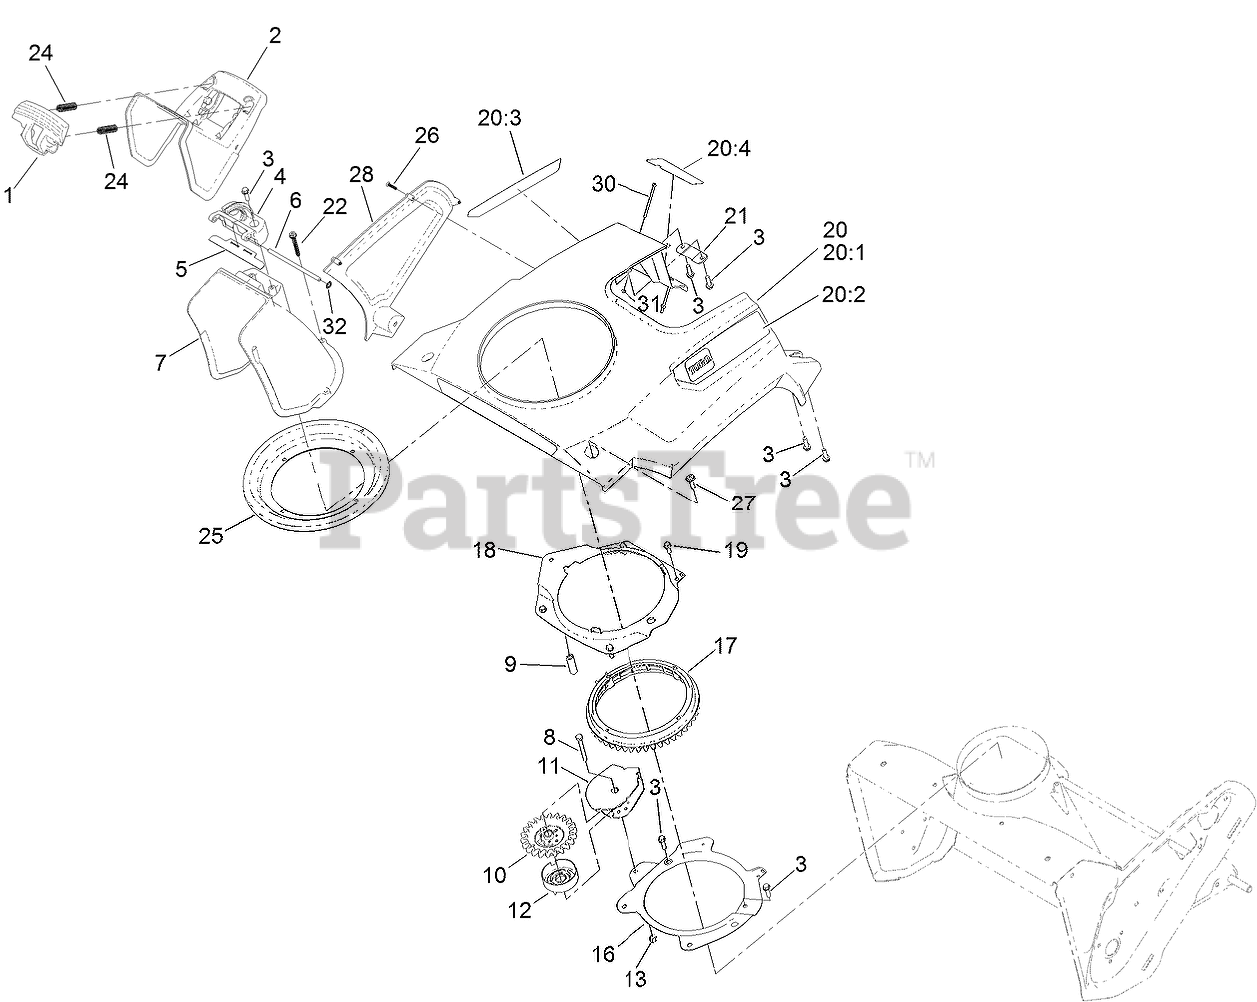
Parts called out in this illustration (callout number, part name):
1	TRIGGER-DEFLECTOR
2	DEFLECTOR-CHUTE, CE
3	SCREW-HWH
4	HINGE-RATCHET, DEFLECTOR
5	SEAL-DEFLECTOR
6	HINGE PIN-DEFLECTOR
8	SCREW-HH
9	SPACER-SLEEVE, PINION
10	PINION-GEAR
11	BRACKET-PINION
12	RETAINER-CABLE
13	NUT-LOCK, NI
16	RING-SUPPORT, CHUTE
17	RING-CHUTE, GEAR
18	RETAINER-RING, CHUTE
19	SCREW-HWH
20	SHROUD ASM, W/DECALS
20:1	SHROUD ASM, W/ARTWORK
20:2	DECAL- SHROUD LH
20:3	DECAL-SHROUD RH
20:4	DECAL-ENGINE, ELECTRIC START
21	RETAINER-SHROUD
22	SCREW-PLASTITE
24	SPRING-COMPRESSION
25	SEAL-RING, CHUTE
26	SCREW-PPH
27	SCREW-PPH
28	COVER-SIDE
30	SCREW-HWH
31	NUT-HEX
32	RING-RETAINING
